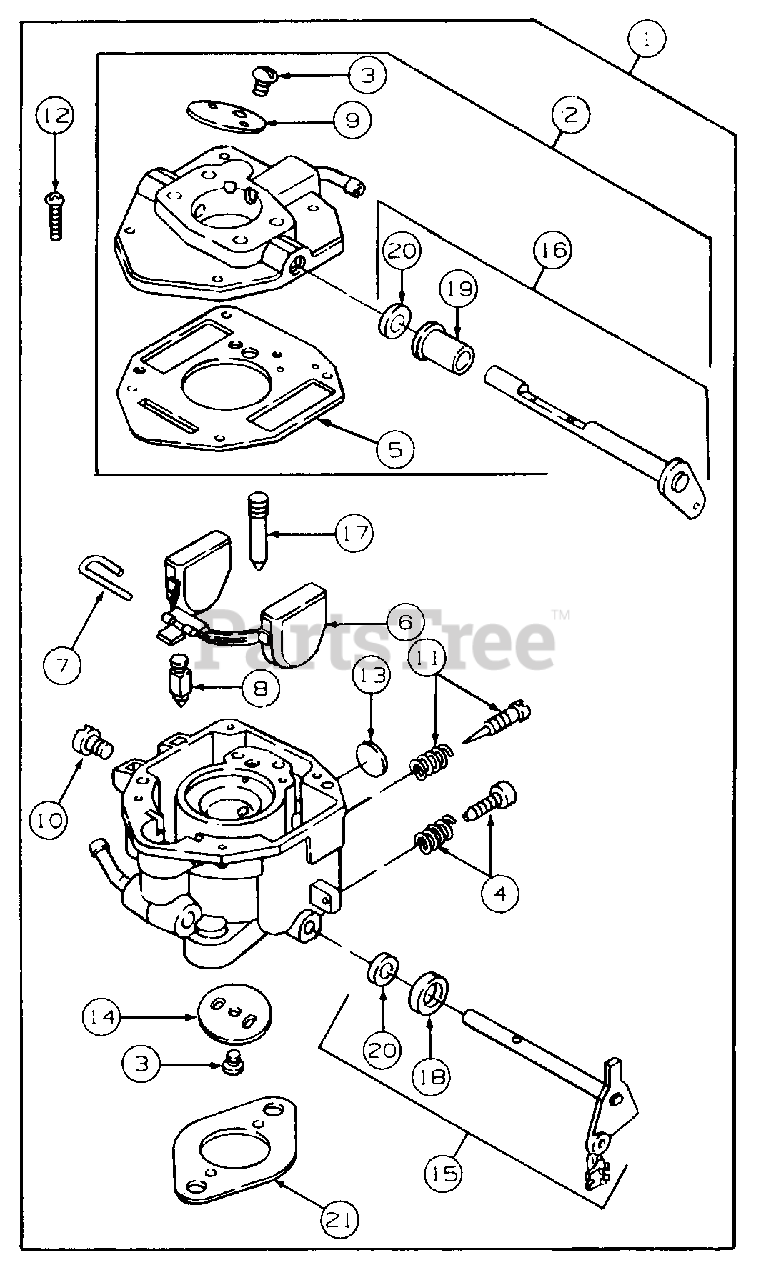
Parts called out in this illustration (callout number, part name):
1	Carburetor Assy
2	Body, Upper Carburetor
3	Screw, Valve Mounting
4	Screw, Throttle Adjustment
5	Gasket, Intake Elbow
6	Float Assy
7	Pin, Float Hinge
8	Valve, Fuel Inlet
9	Valve, Choke
10	Jet, Main
11	Valve, Idle Adjusting Needle
12	Screw, Upper Body Mounting
13	Plug, Welch
14	Valve, Throttle
15	Shaft, Throttle
16	Shaft, Choke
17	Jet, Slow Speed
18	Collar, Throttle
19	Collar, Choke
20	Seal, Shaft
21	Gasket, Carburetor Mounting
